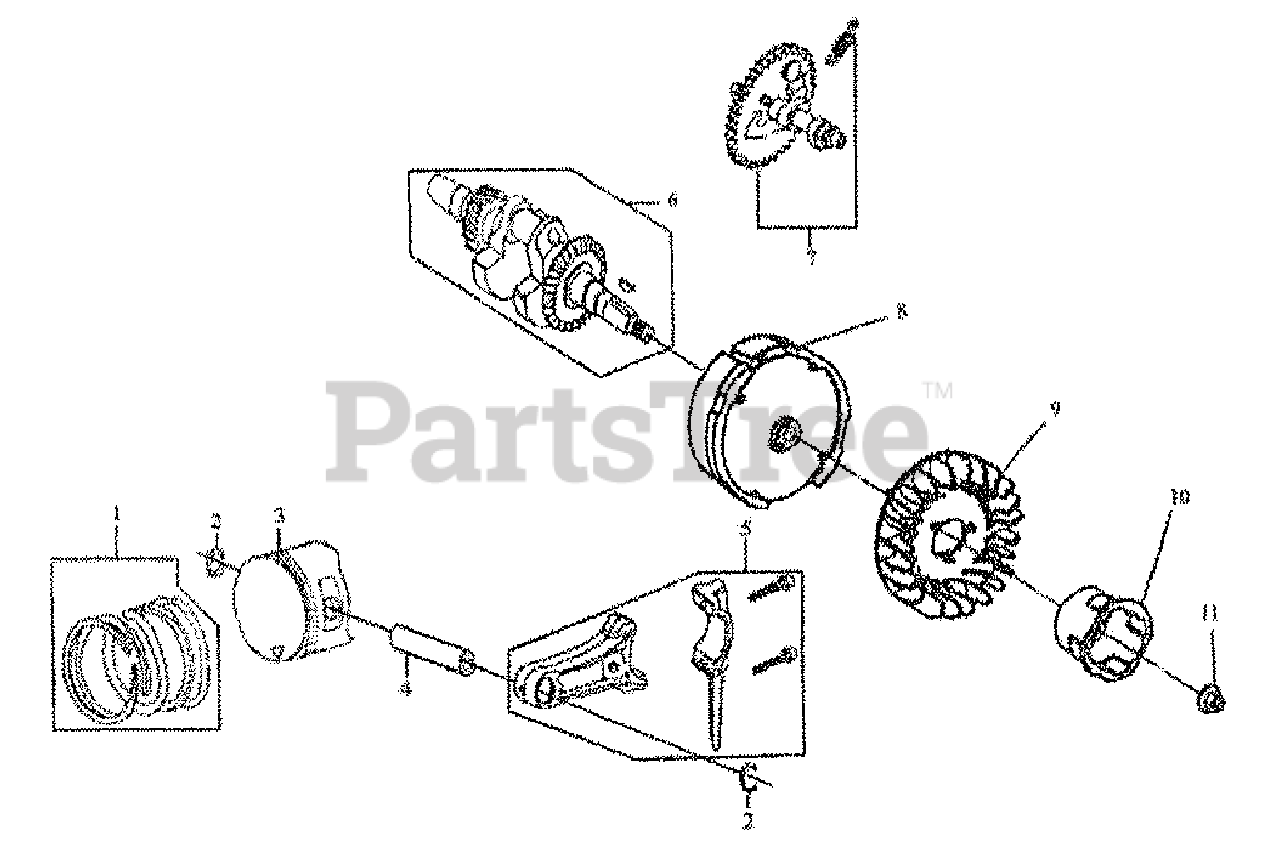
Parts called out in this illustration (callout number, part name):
1	RING SET' PISTON
2	CIRCLIP' PISTON RING
4	PIN' PISTON
5	ROD ASSY' CONNECTING
6	CRANKSHAFT ASSY.
7	CAMSHAFT ASSY
9	FAN' FLYWHEEL
10	CUP' STARTING
11	NUT' M 14X1.5
